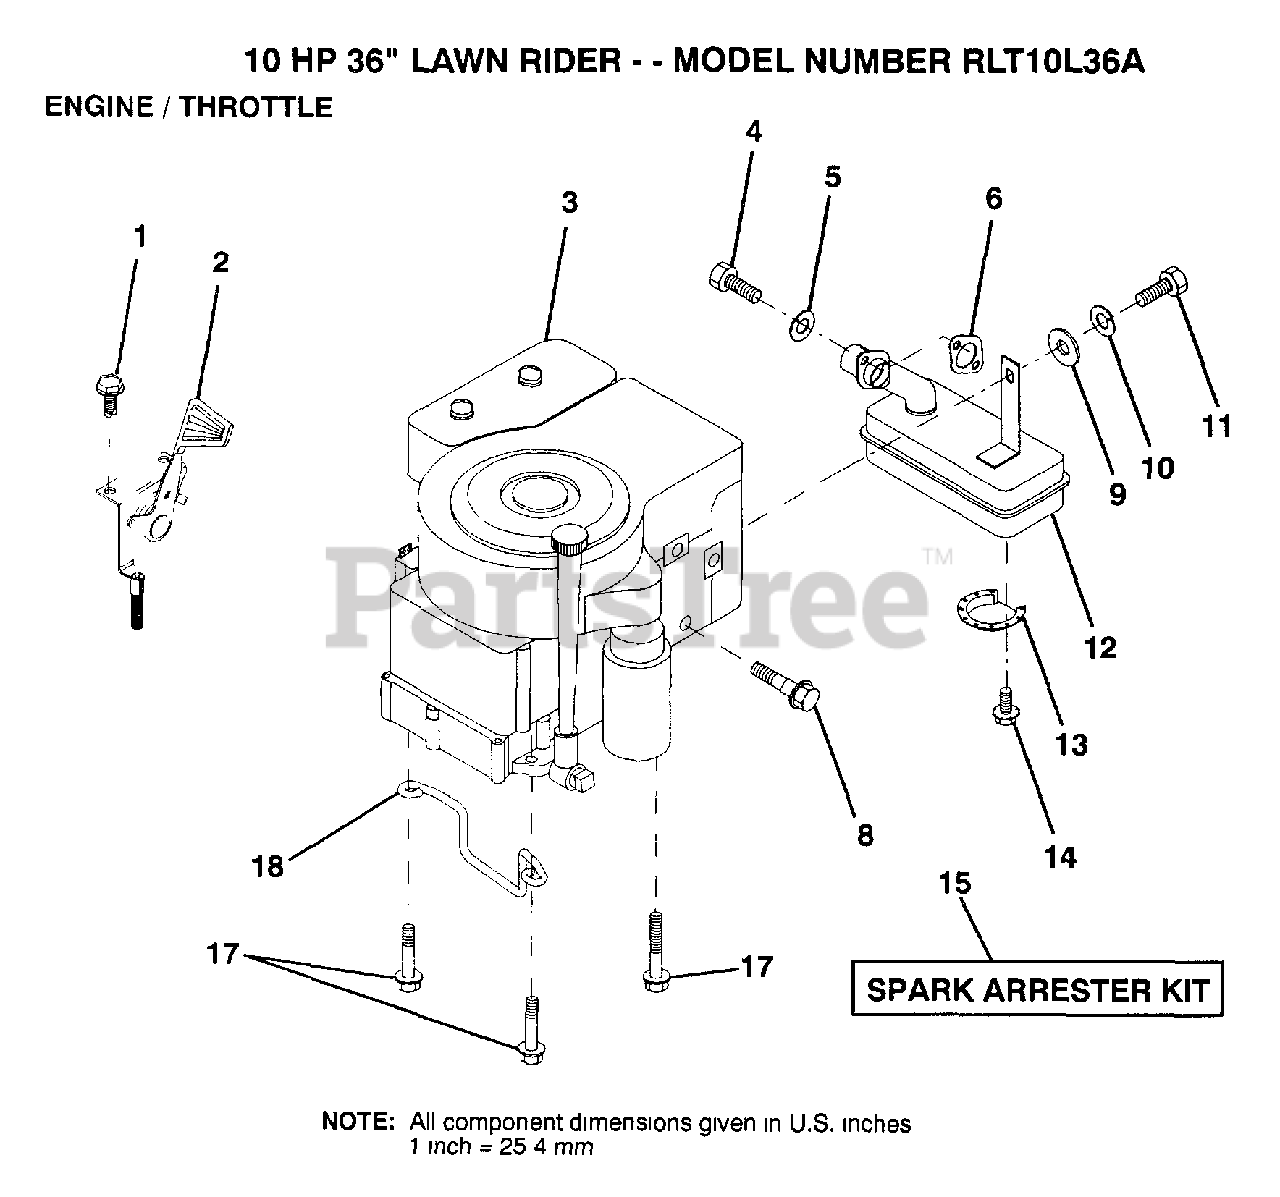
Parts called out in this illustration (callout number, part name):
1	SCREW
2	THROTTLE CONTROL
4	SCREW
5	LOCKWASHER
8	BOLT T
10	LOCKWASHER
13	DEFLECTOR.222573
17	SCREW LT
18	"KEEPER,DR BELT GR"
